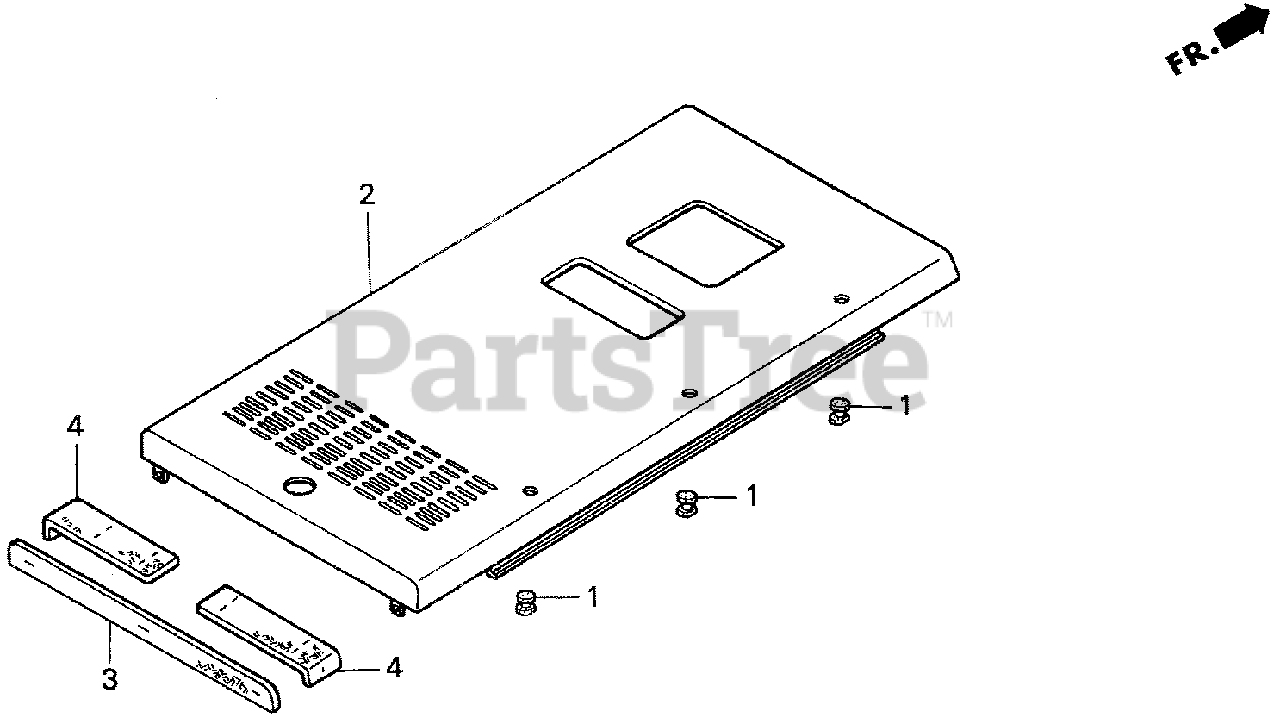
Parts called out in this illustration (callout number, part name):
2	COVER (UPPER) *B132* (JOHN BLUE)
3	INSULATOR, COVER (UPPER) (C)
4	INSULATOR, COVER (UPPER) (D)
